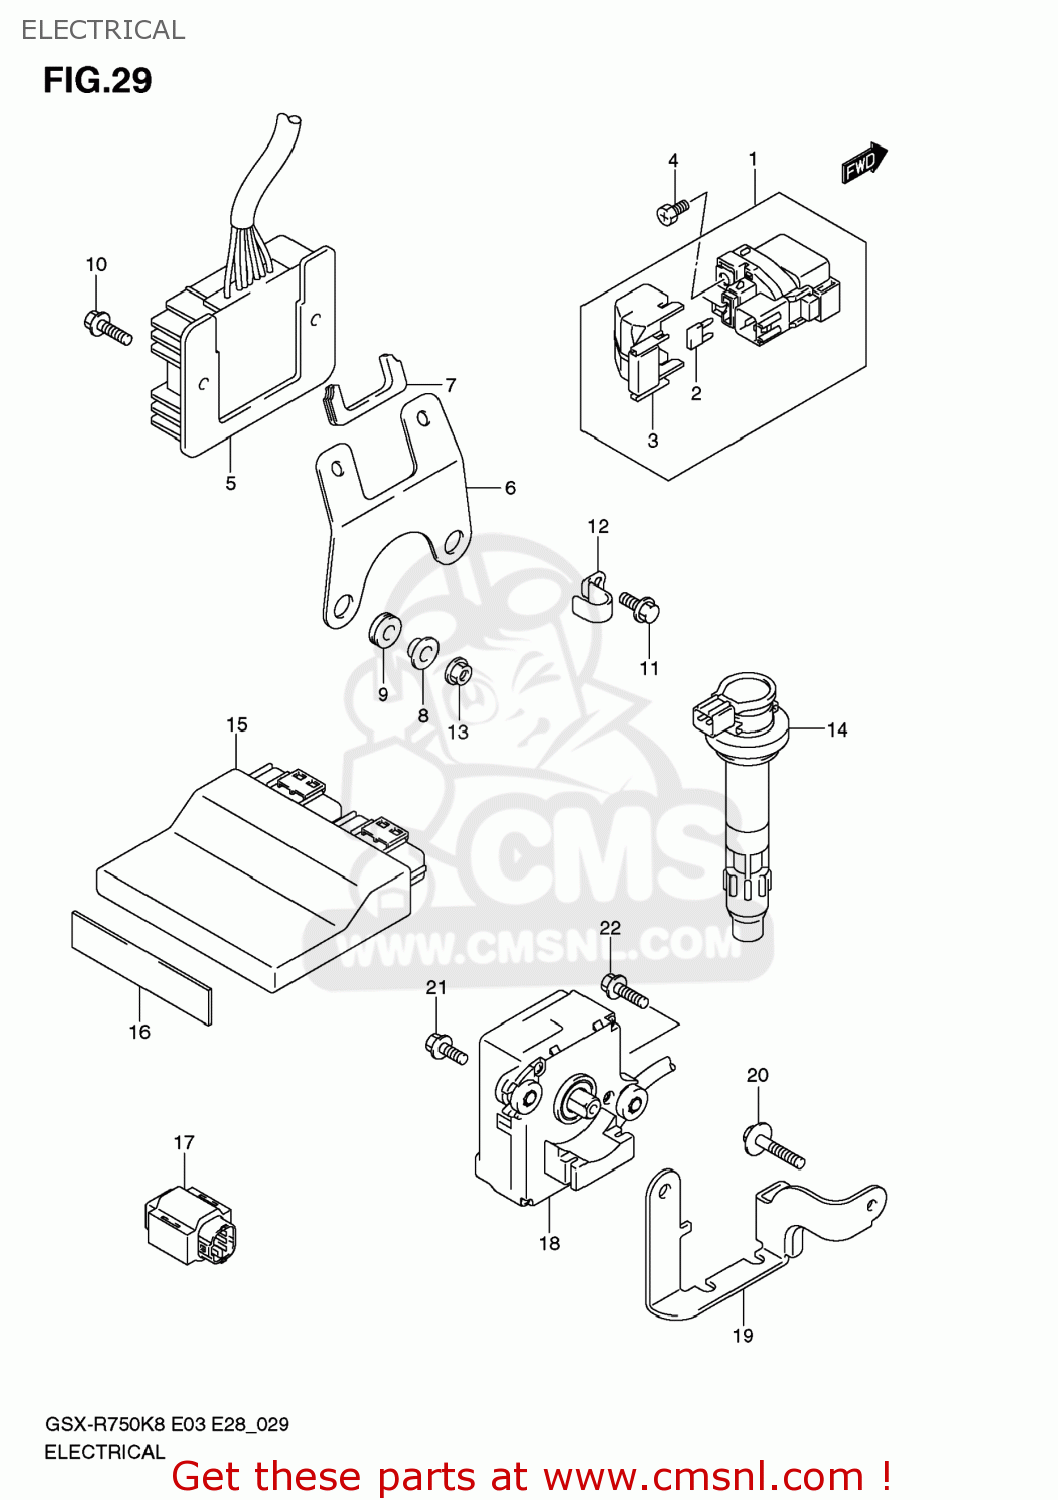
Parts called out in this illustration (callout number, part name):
1	RELAY ASSY,STARTING MOTOR
2	FUSE(30A)
3	COVER
4	SCREW(6X8)
5	RECTIFIER ASSY
6	BRACKET,RECT FTG
7	MOLD,RECTIFIER BRKT
8	SPACER(6.2X8.4X6.9)
9	CUSHION
10	BOLT
11	BOLT
12	CLAMP
13	NUT
14	COIL ASSY,IGNITION
15	CONTROL UNIT,FI
16	PROTECTOR(20X90)X2
17	SENSOR ASSY,FUEL CUT
18	ACTUATOR ASSY,EXHAUST CONTROL
19	HOLDER,ACTUATOR
20	BOLT(6X30)
21	BOLT
22	BOLT(6X25)
